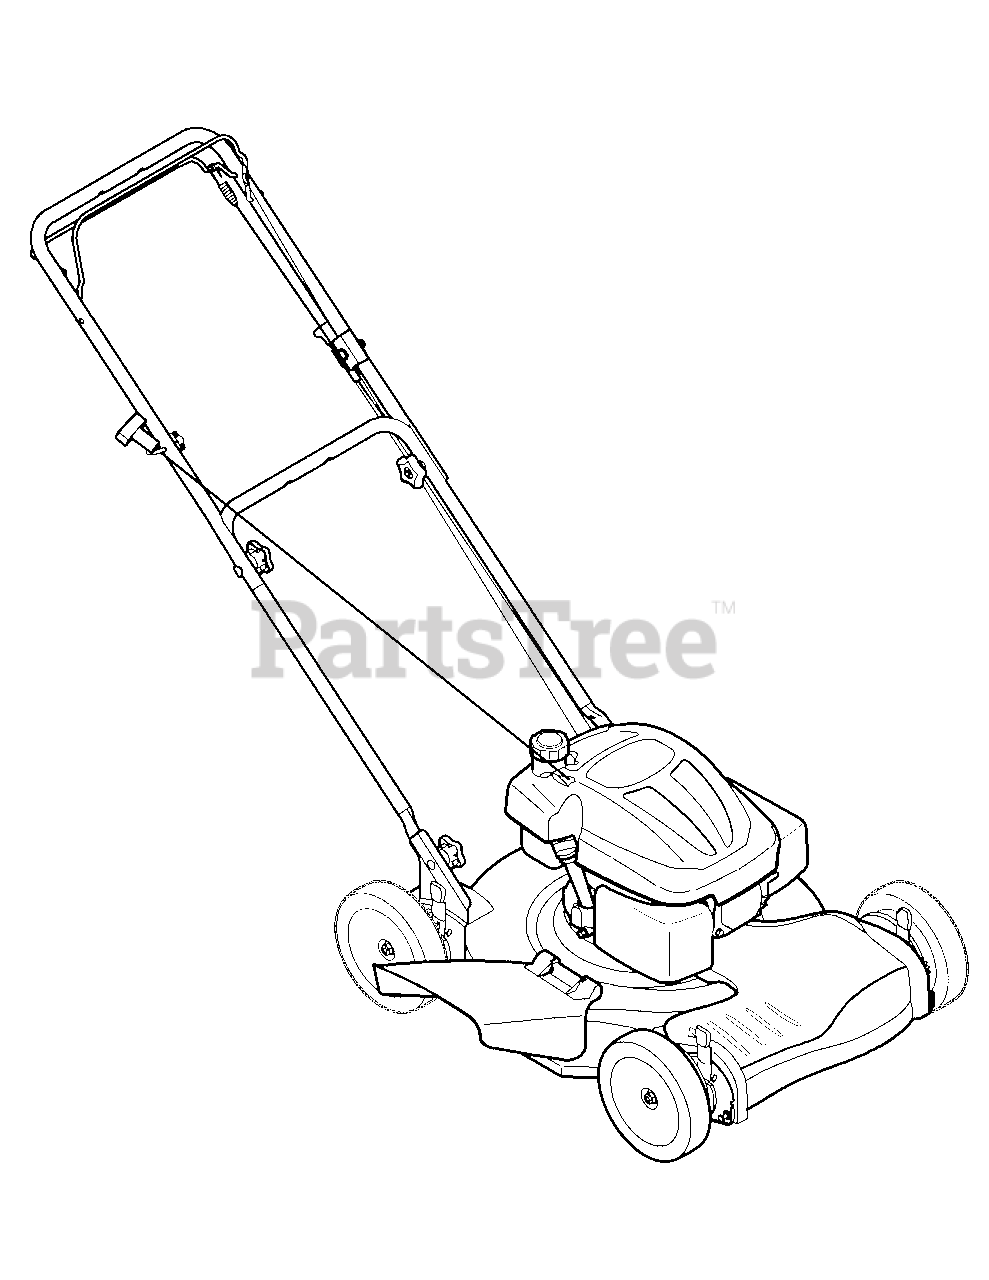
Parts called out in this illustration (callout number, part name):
NA	Pre-Filter
NA	Ignition Key
NA	Grass Bag
